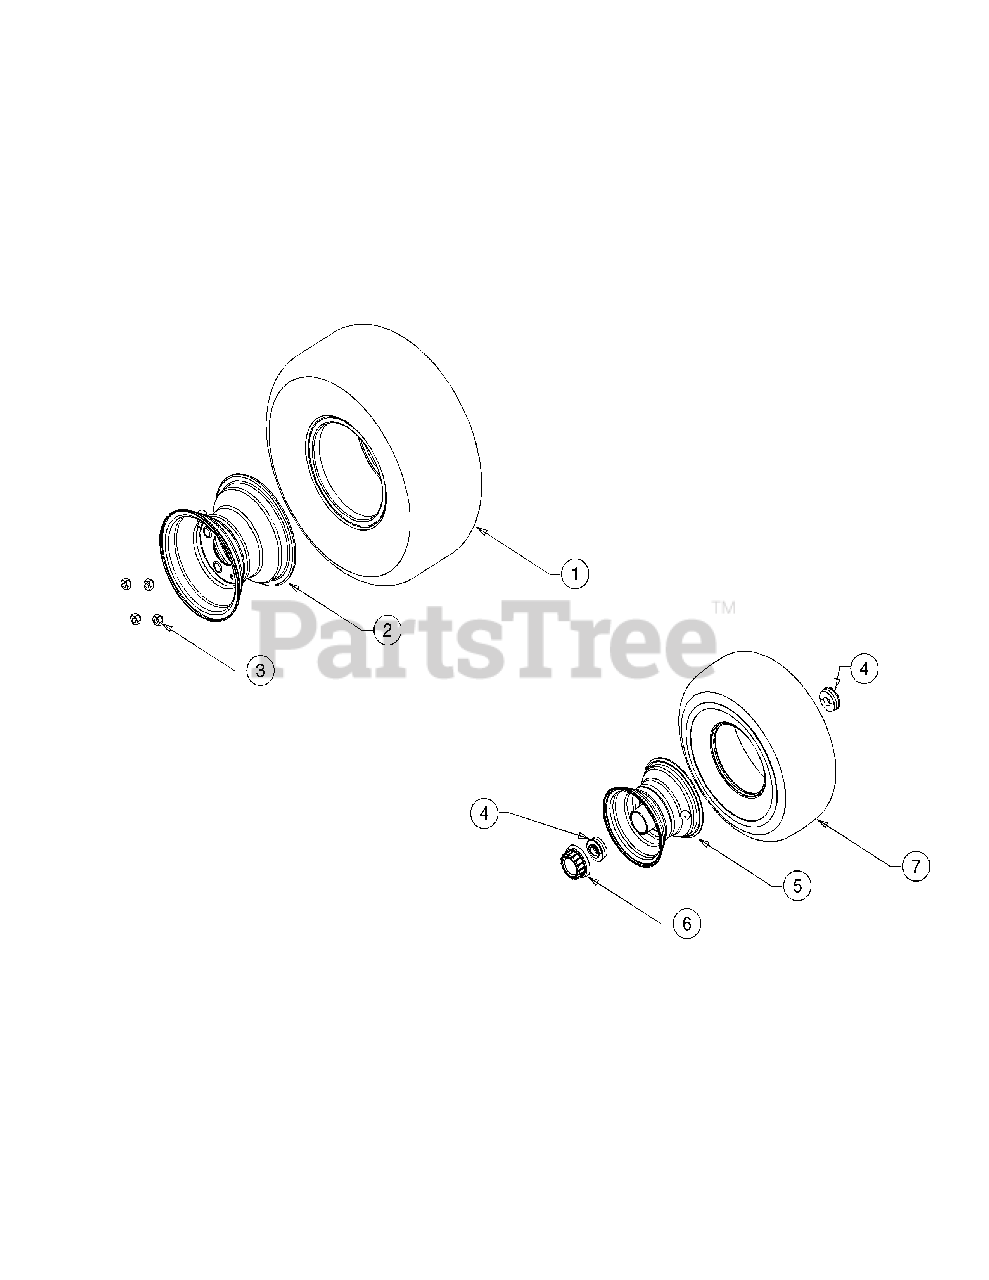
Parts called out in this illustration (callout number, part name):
1	Wheel, Complete, 22 x 9.5 x 12
1	Tire, Turf, Cub Cadet 22 x 9.5 x 12
2	Rim Assembly, 12 x 7 (4-Lug)
3	Lug Nut, 7/16-14
4	Bearing, Flange .760 X 1.00 X 1.20LG
4	Bearing, Flange .760 ID w/grease fitting
5	Rim Assembly, 6 x 4.5
7	Wheel, Complete, 15 x 6 x 6
7	Tire, Turf, Cub Cadet 15 x 6 x 6
